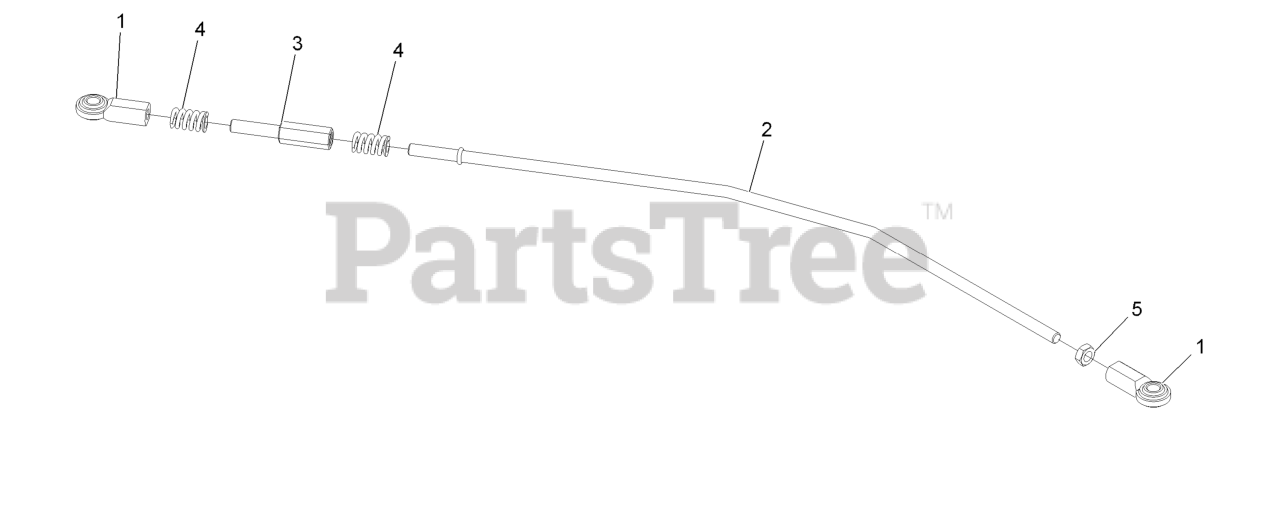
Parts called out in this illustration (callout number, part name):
1	JOINT-BALL, END
2	LINK-LOWER,MOTION CONTROL
3	ROD-ADJUSTMENT
4	SPRING-COMPRESSION
5	NUT-HJ
